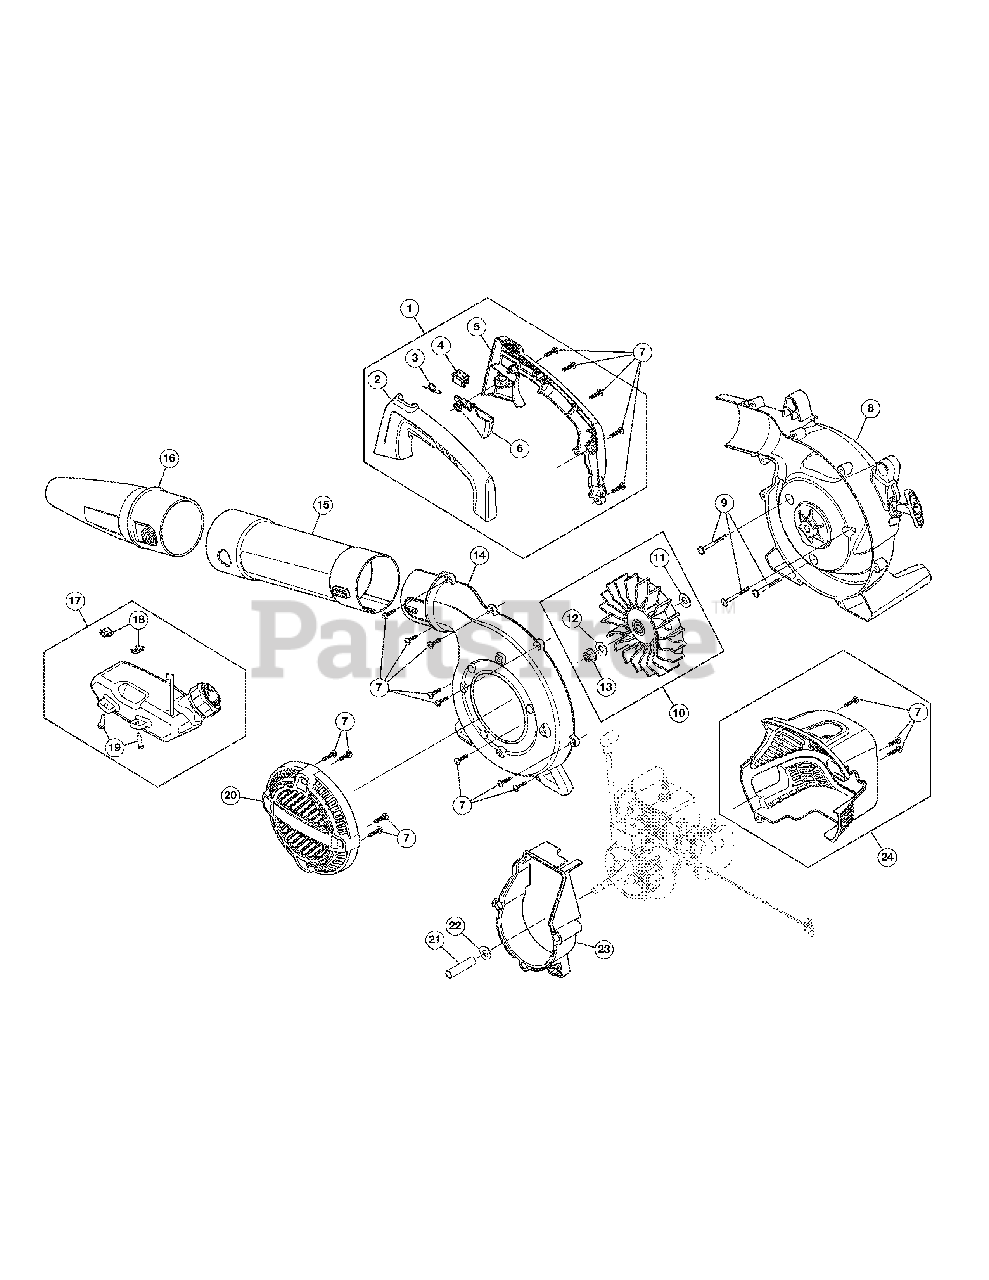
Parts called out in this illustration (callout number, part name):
1	Handle Assembly
2	Handle (LH)
3	Trigger Spring
4	On/Off Switch
5	Impeller Housing Handle (RH)
6	Throttle Trigger
8	Impeller Housing Assembly (RH)
10	Impeller Assembly
11	Washer
12	Lock Washer
14	Impeller Housing Assembly (LH) (Incl. 7)
15	Upper Blower Tube
16	Blower Nozzle
17	Fuel Tank Assembly
18	U-Shaped Nut
20	Intake Cover (Incl. 7)
21	Shaft Spacer
22	Washer
23	Engine Adapter (Incl. 9)
24	Engine Cover Housing (Incl. 7)
